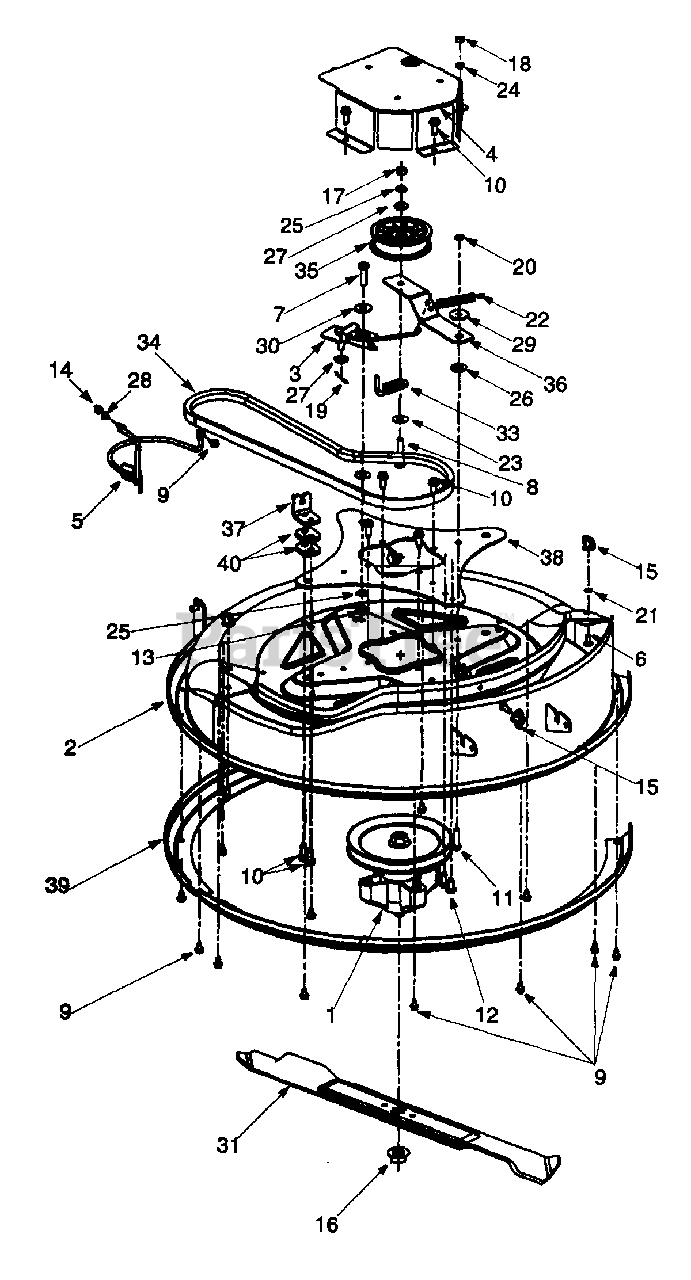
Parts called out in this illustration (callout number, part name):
1	Spindle Assembly
7	Hex Bolt 3/8-24 x 1.25 Grade 8
8	Hex Screw 3/8-16 x 1.75 Gr. 5
9	Self-Tapping Washer Head Hex Screw 1/4-20 x .5
10	Hex Washer Self-Tapping Screw 5/16-18 x .75
11	Hex Cap Scr. 5/16-24 x 1.25 (Gr. 5)
12	Torx Head Screw 5/16-18 x.75
13	Hex Nut 3/8-24
14	Hex Nut 1/4-20
15	Wing Nut With Bell Washer
16	Flange Nut 5/8-18
17	Hex Nut 3/8-16
18	Hex Nut 5/16-24
19	Cotter Pin
20	Speed Nut
21	Push Nut
22	Extension Spring
23	Flat Washer 3/8 x 1.00 x .030
24	Lock Washer 5/16
25	Lock Washer 3/8
26	Bushing
27	Flat Washer .406 x .875 x .059
28	Lock Washer
29	Flat Washer .330 x 1.25 x .120
30	Spacer
33	Belt Keeper
34	V Belt
35	Flat Idler Pulley
